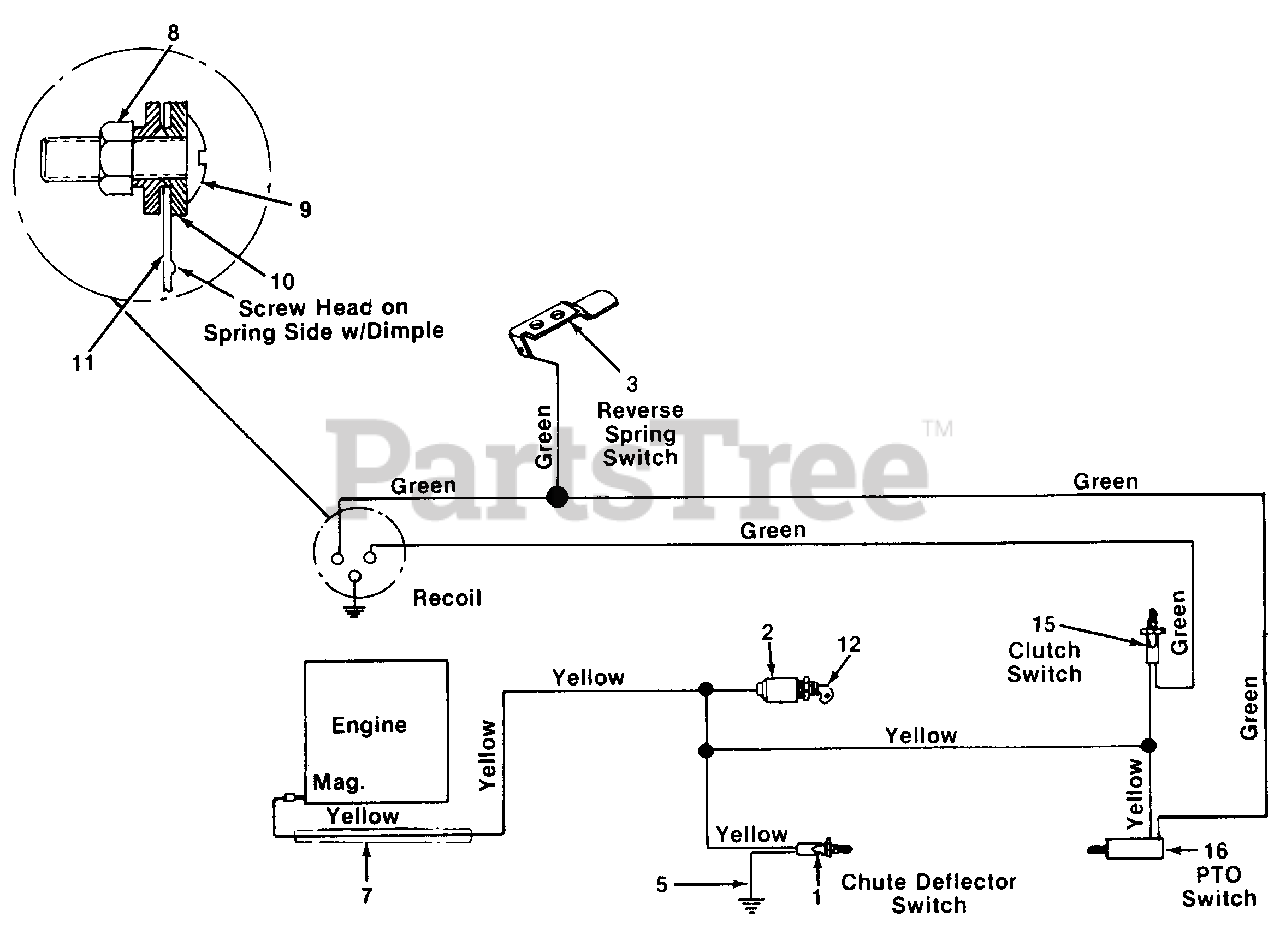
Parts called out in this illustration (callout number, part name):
1	Safety Switch
2	Key Switch
3	Spring Switch
7	Convoluted Conduit 24" Lg.
8	Hex Nut #10-24
9	Truss Mach. Scr. #10-24 x .62
10	Fiber Washer
11	Spring Switch
12	Ignition Key
15	Safety Switch
16	Safety Switch
